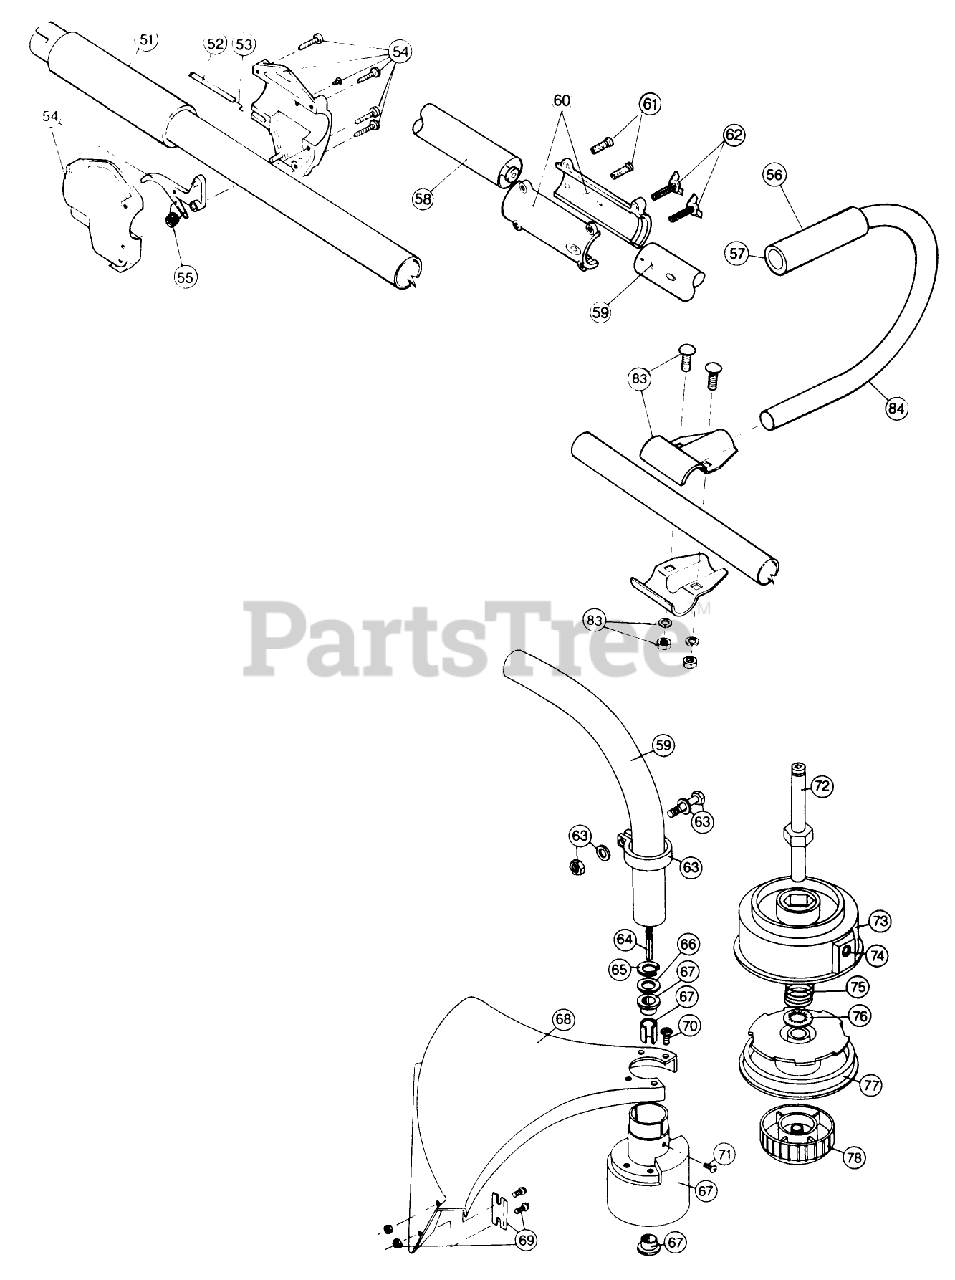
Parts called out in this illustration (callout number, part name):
53	THROTTLE CABLE WIRE
54	THROTTLE TRIGGER ASM
55	THROTTLE TRIGGER SPRING
56	HANDLE NITRILE GRIP
57	TUBE CLOSURE
62	ADJUSTMENT KNOB SET
65	RETAINING RING
66	WASHER
67	BUSHING HSG ASM
69	BLADE ASM
70	GUARD MOUNTING SCREW
71	ANTI-ROTATION SCREW
74	EYELET
75	SPRING
76	RETAINER WASHER
77	REEL - INNER
79	LOOP LINE
82	COMPLETE CUTTING HD ASM
85	STRAP SHOULDER ACC
